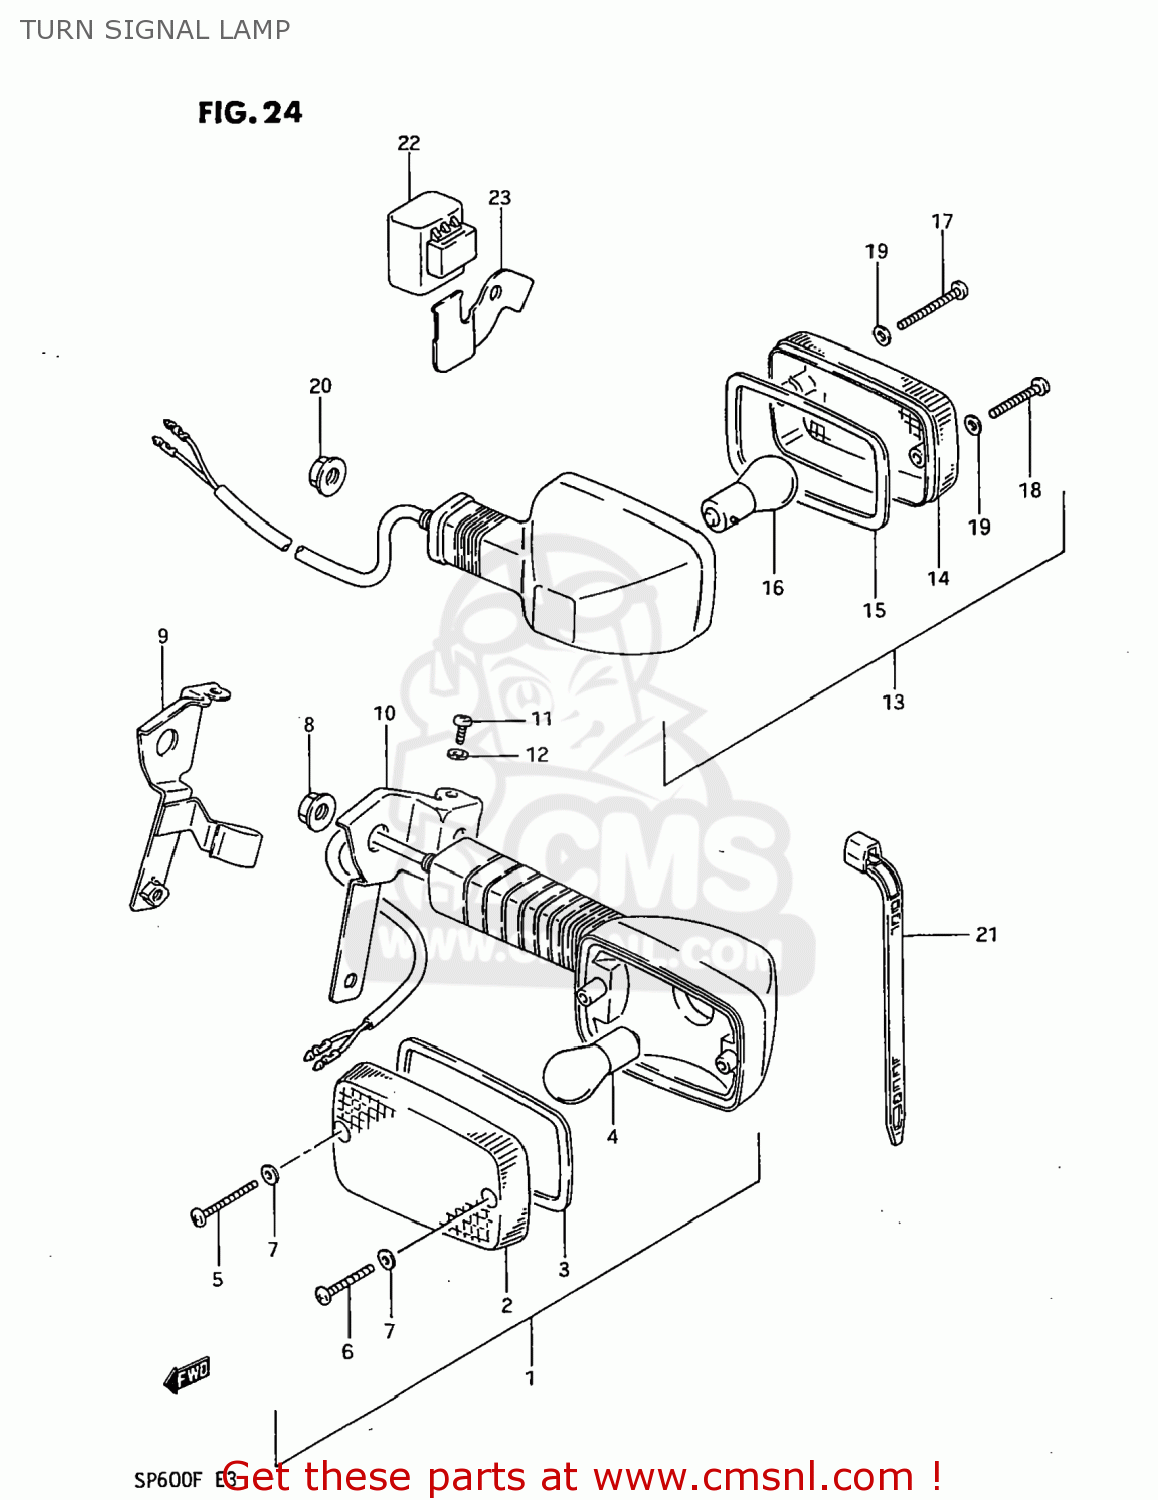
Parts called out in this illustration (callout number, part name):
1	LAMP ASSEMBLY,FRONT TURN SIGNAL
2	LENS,FR
3	GASKET (NAS)
4	BULB(12V23W,STANLEY,A4577A)
5	SCREW,TURN SIG LENS FITTING
6	SCREW
7	GASKET (NAS)
8	NUT
9	BRACKET,FRONT TURN SIGNAL
10	BRACKET,FRONT TURN SIGNAL
11	SCREW
12	WASHER,LOCK
13	LAMP ASSEMBLY,REAR TURN SIGNAL
14	LENS,RR
15	GASKET (NAS)
16	BULB(12V23W,STANLEY,A4577A)
17	SCREW,TURN SIG LENS FITTING
18	SCREW
19	GASKET (NAS)
20	NUT
21	CLAMP(L:125)
22	RELAY ASSEMBLY,TURN SIGNAL
23	BRACKET,TURN SIGNAL RELAY
